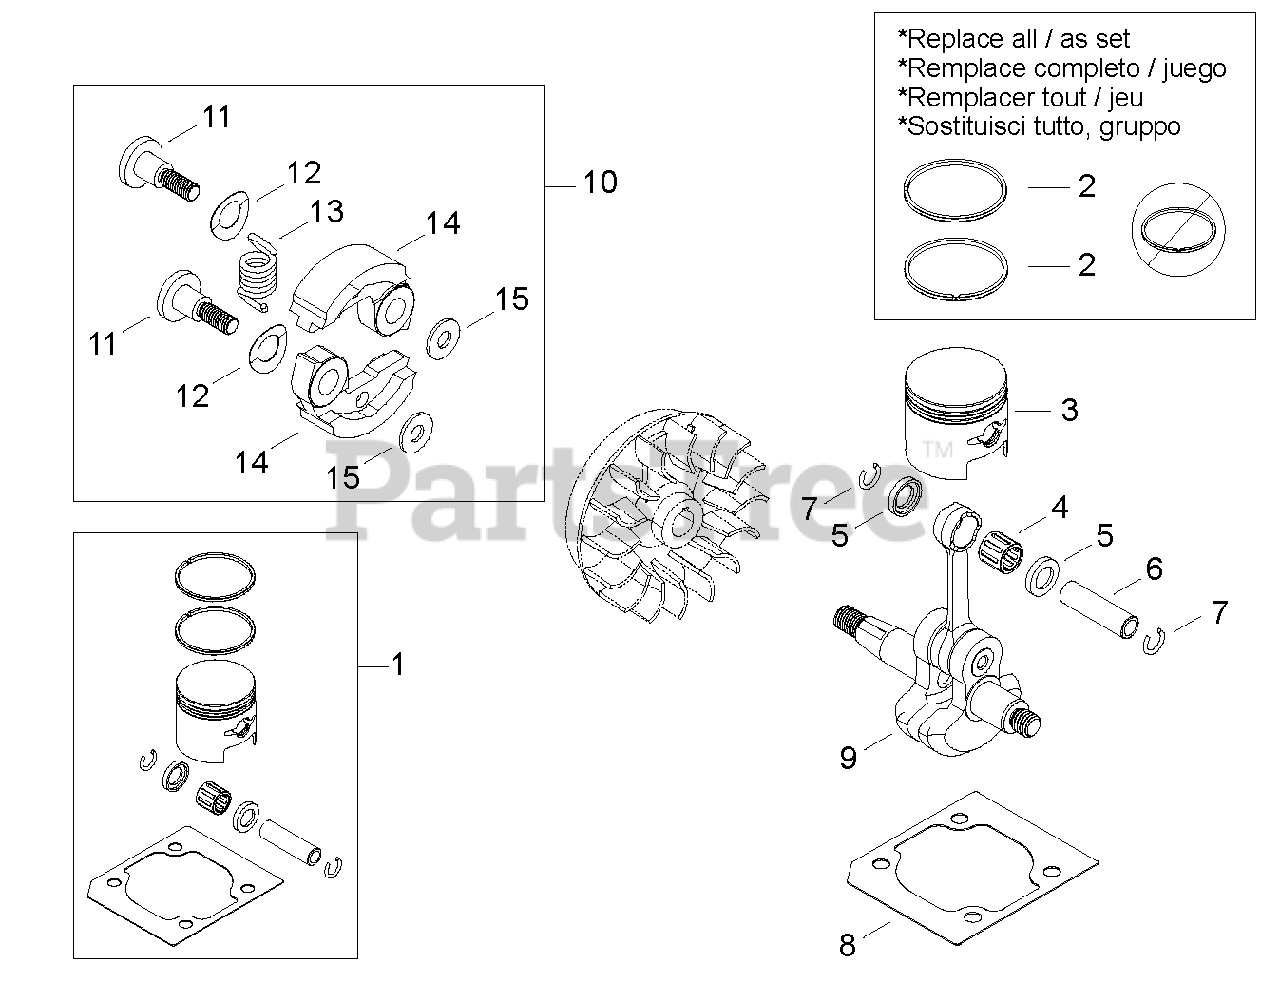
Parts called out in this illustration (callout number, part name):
2	RING, PISTON
3	PISTON
3-1	PISTON KIT
4	BEARING, NEEDLE 8
5	WASHER, THRUST 8
6	PIN, PISTON 8
7	RING, SNAP
8	GASKET, CYLINDER
9	CRANKSHAFT ASSY
10	CLUTCH ASSY
11	BOLT, CLUTCH
12	WASHER, SPRING
13	SPRING, CLUTCH
14	SHOE, CLUTCH
15	WASHER 6 MM
